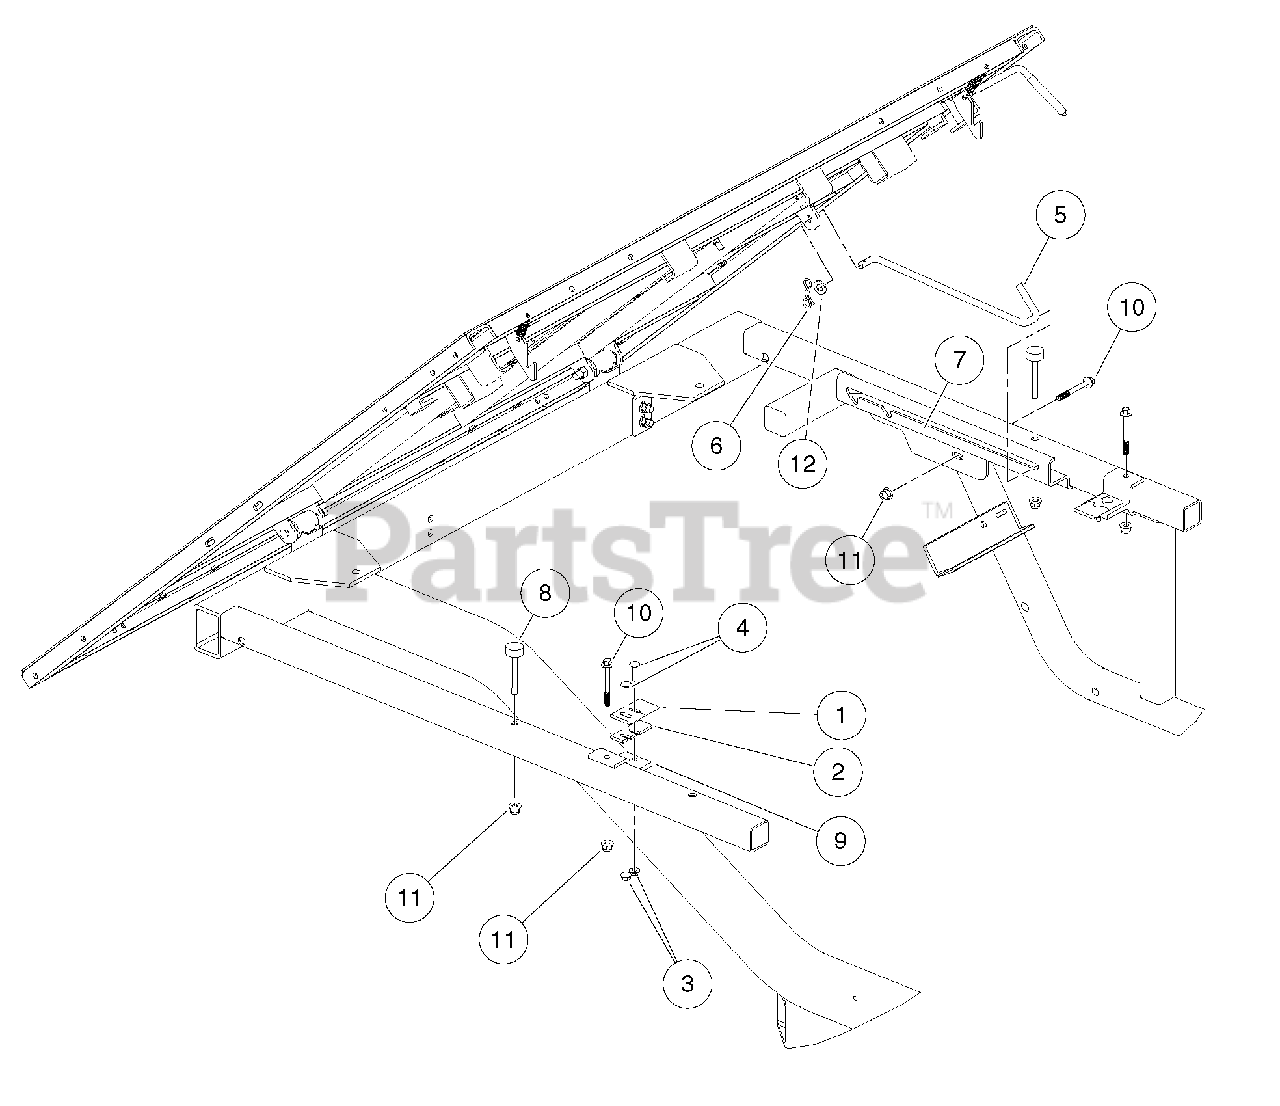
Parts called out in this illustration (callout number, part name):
1	Latch Plate, Tilt Bed
2	Latch Plate Shim
3	Locknut, 1/4-20 Hex Whiz
4	Bolt, Carriage, 1/4-20 X 1.0
6	Pin, Bow Tie Locking
7	Track, Prop Rod
8	Bumper, Bed, Mtg, Front
9	Bracket, Latch, Bed
10	Bolt Flanged Head, M8 X 1.25 X 65
11	Lock Nut, Flg M8 X 1.25 Nylon
12	Washer, 3/8 Type A Flat
